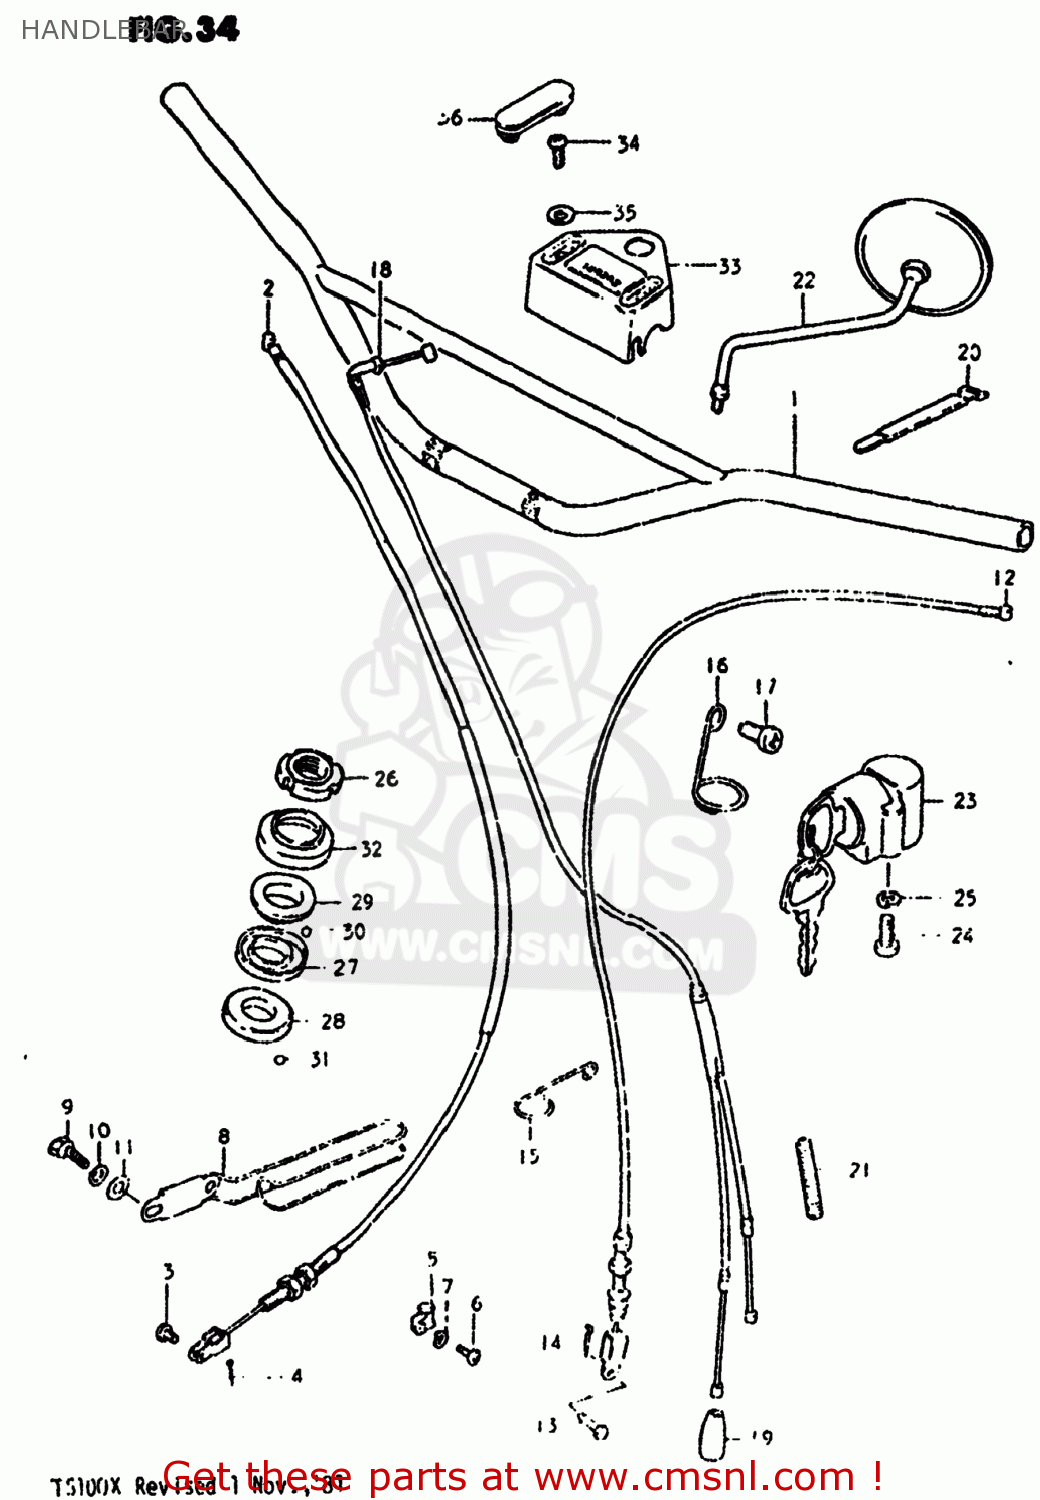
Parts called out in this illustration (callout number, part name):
1	HANDLEBAR
2	CABLE ASSEMBLY,FRONT BRAKE
3	PIN(L:13.5)
4	PIN
5	GUIDE,CABLE
6	SCREW
7	LOCK WASHER
8	GUIDE,CABLE
9	BOLT 8X12
10	LOCK WASHER
11	WASHER
12	CABLE ASSEMBLY,CLUTCH
13	PIN(L:15)
14	PIN
15	CLAMP
16	CLIP
17	SCREW
18	CABLE ASSEMBLY,THROTTLE
19	SEAL,DUST(7X18X30)
20	CLAMP L:110
21	PROTECTOR,CABLE
